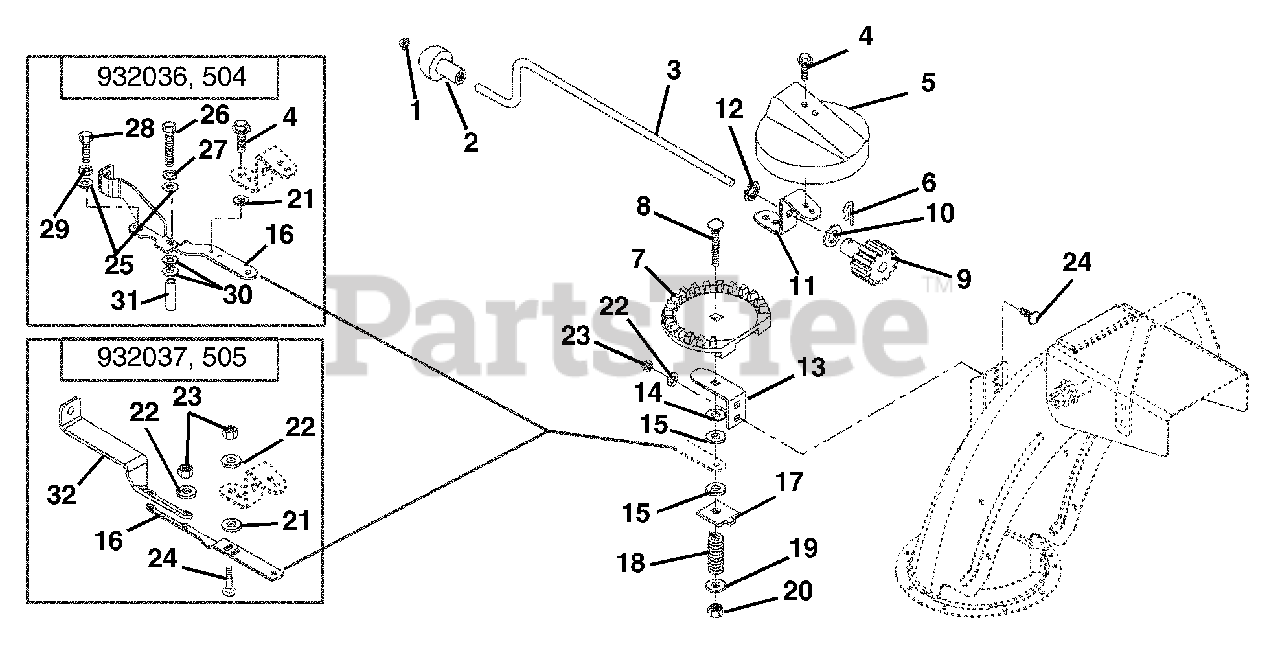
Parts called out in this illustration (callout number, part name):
1	CAP, 3/8 ROD YWZC
3	CRANK, CHUTE
4	@SCR-TAP .25-20X.50 HWH TR YWZ
5	GEAR COVER
6	PIN, SPRING CLIP
7	CHUTE GEAR
8	@BLT-RDHDSQNK .38-16X2.50 G5YZ
9	PINION GEAR W/BRACKET
10	WSHR-FL-STL .630X1.005X.062 YZ
11	BRACKET-GEAR
12	PUSHNUT .625
13	GEAR STRAP
14	WSHR-FL-STL .380X1.50X.062 YWZ
15	FRICTION WASHER
16	BRACKET, CRANK SUPPORT
16	BRACKET, CHUTE SUPPORT
17	FRICTION PLATE
18	SG-COMP .187X.56X1.62
19	@WSHR-FL-STL.406X.812X.065 YWZ
20	@NUT-LK-CTR .38-16 YWZC
21	@WSHR-FL-STL.281X.62X.065 YWZC
22	@WSHR-LK .25X.062 REG YWZC
23	@NUT-HEX .25-20 YWZC
24	@BLT-RDHDSQNK .25-20X.75 G5YZ
25	WSHR-FL-STL .328X.875X.062YWZC
26	@NUT-HEX .25-20 YWZC
26	@BLT-HEX .25-20X1.50 GR5 YWZC
27	WSHR-LK .250X.077 HVY YWZC
28	@BLT-HEX .31-18X.75 GR5 YWZC
29	WSHR-LK .312X.097 HVY YWZC
30	@WSHR-FL-STL.38X.875X.083 YWZC
31	SPACER .280X.625X.640
32	SUPPORT, CHUTE CRANK
